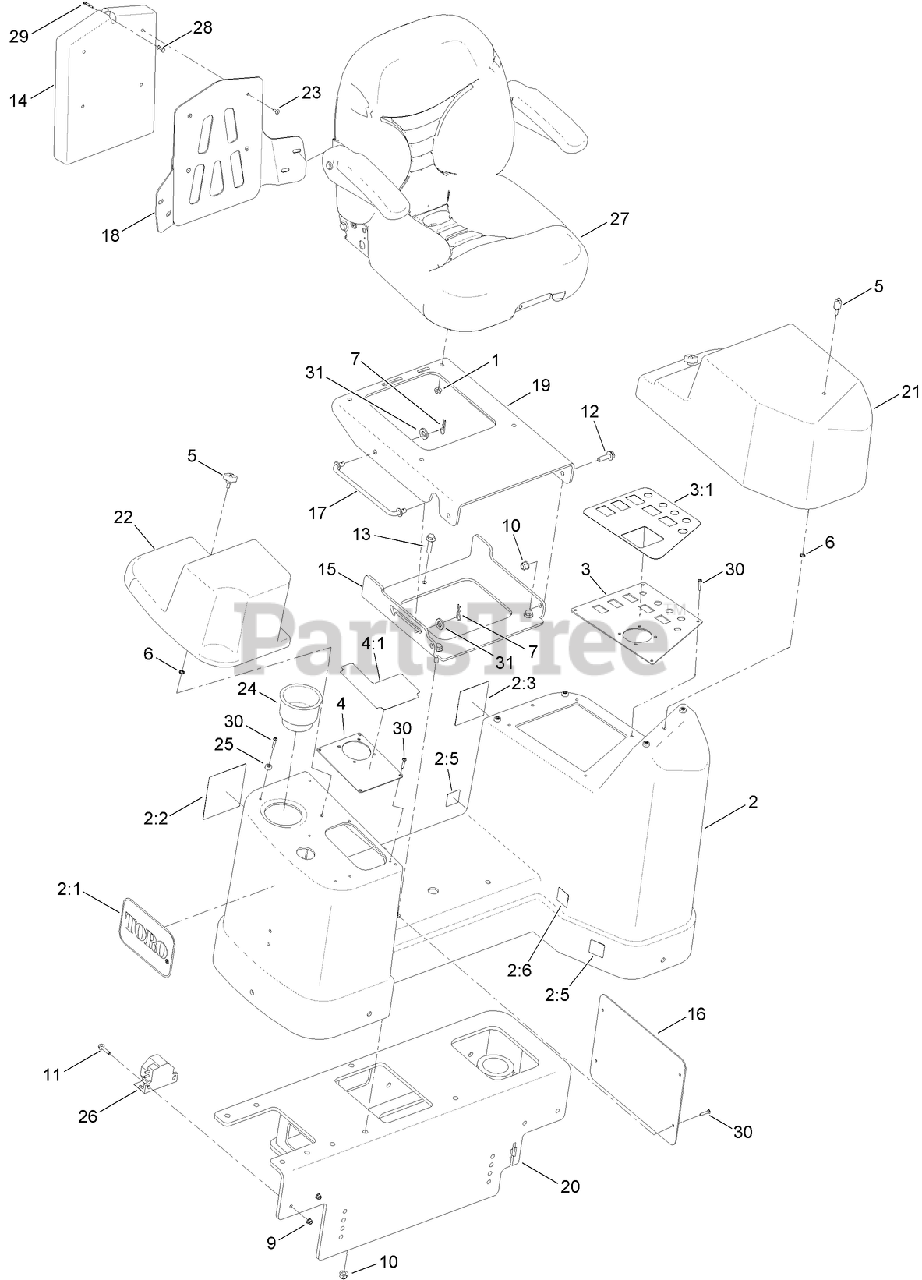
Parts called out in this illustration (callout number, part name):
1	NUT-HF, NI
2	OPERATOR CONSOLE ASM
2:1	DECAL
2:2	DECAL-SHOCK DANGER
2:3	DECAL-DANGER, NO RIDERS (FRONT)
2:5	DECAL-SEAT ADJUST
2:6	DECAL-SEAT SLIDE
3	SWITCH PLATE ASM
3:1	DECAL-JOYSTICK, LEFT
4	JOYSTICK MOUNTING PLATE ASM
4:1	DECAL-JOYSTICK, RIGHT
6	RING-RETAINING
7	PIN-HAIR
9	NUT-FLANGE, NI
10	NUT-LOCK, NI
11	SCREW-HHF
12	SCREW-HHF
13	SCREW-HHF
14	HOLDER-MANUAL, OPERATOR
15	PLATE-SEAT MOUNT, BOTTOM
16	PLATE-SEAT, INSIDE PANEL
17	ROD-PROP, SEAT
18	PLATE-MOUNT, MANUAL
19	PLATE-SEAT MOUNT, TOP
20	CONSOLE-OPERATORS
21	COVER-CONSOLE, LH
22	COVER-CONSOLE, RH
23	RIVET-BLIND
24	CUP-HOLDER
25	GROMMET-RUBBER
26	ALARM-BACKUP
27	OPERATOR SEAT ASM (STATIC)
28	POST-MANUAL
29	LANYARD
30	SCREW-PPH
31	WASHER-FLAT
